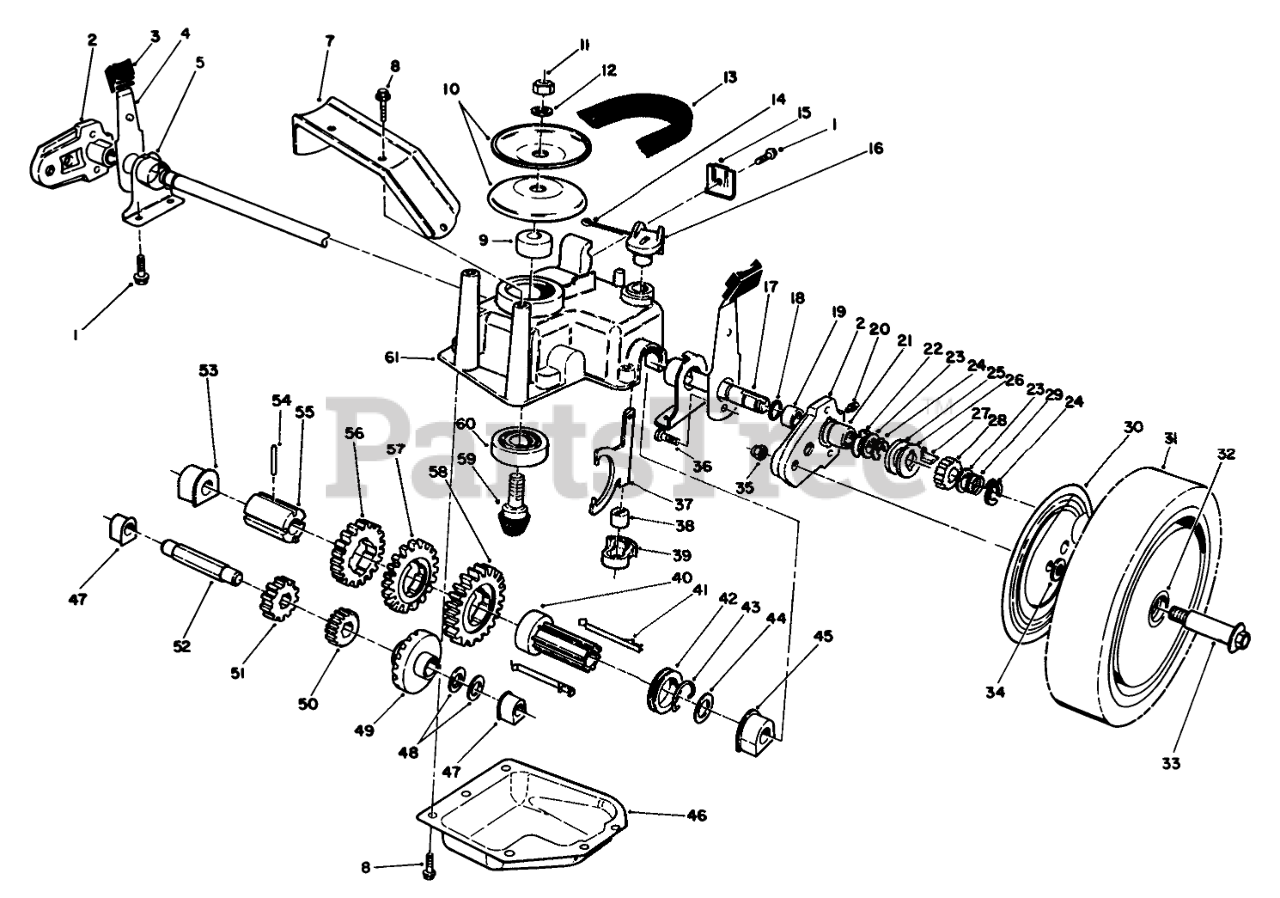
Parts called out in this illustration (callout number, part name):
1	SCREW-HWHTF
2	Pivot Arm Assembly (Incl. Ref. #19-21)
3	KNOB-ARM
4	SPRING ARM ASM
5	CAP-END
7	Bracket-BeltGuide
8	SCREW-HWHTF
9	SPACER
10	Pulley Half
11	NUT-HEX
12	WASHER-FLAT
13	V-BELT
14	PIN-COTTER
15	CABLE CLAMP
16	Lever-Shift
17	SHAFT-OUTPUT
18	O-RING
19	BUSHING
20	FITTING-GREASE
21	BEARING-ROLLER
22	WASHER-ARM, PIVOT
23	WASHER-THRUST, KEYED
24	RING-CLIP, LOCKING
25	RING-FRICTION
26	WASHER-CLUTCH
27	KEY-ROCKING, LH
28	GEAR-PINION
29	SPRING-COMPRESSION
30	WHEEL COVER
31	Wheel Tire & Gear Assy. (Incl. Ref. #32)
32	BUSHING
33	WHEEL BOLT
34	WASHER
35	Nut
36	SCREW-HSH, THREAD FORMING
37	YOKE-SHIFT
38	BUSHING-YOKE
39	RETAINER-FORK, SHIFT
40	Sleeve-Shift Key
41	SHIFT KEY
42	SHIFT COLLAR
43	CLIP-SPRING
44	WASHER-PLAIN
45	BUSHING-OUTPUT
46	Cover-Gearcase
47	BUSHING
48	WASHER-THRUST
49	Gear-Bevel
50	PINION-20T
51	PINION-25T
52	SHAFT-INTERMEDIATE
53	BUSHING
54	PIN-SPRING
55	SLEEVE-GEAR
56	GEAR-39T
57	GEAR-44T
58	GEAR-49T
59	Gear-Pinion
60	BEARING-BALL
61	CASE-GEAR, UPPER
